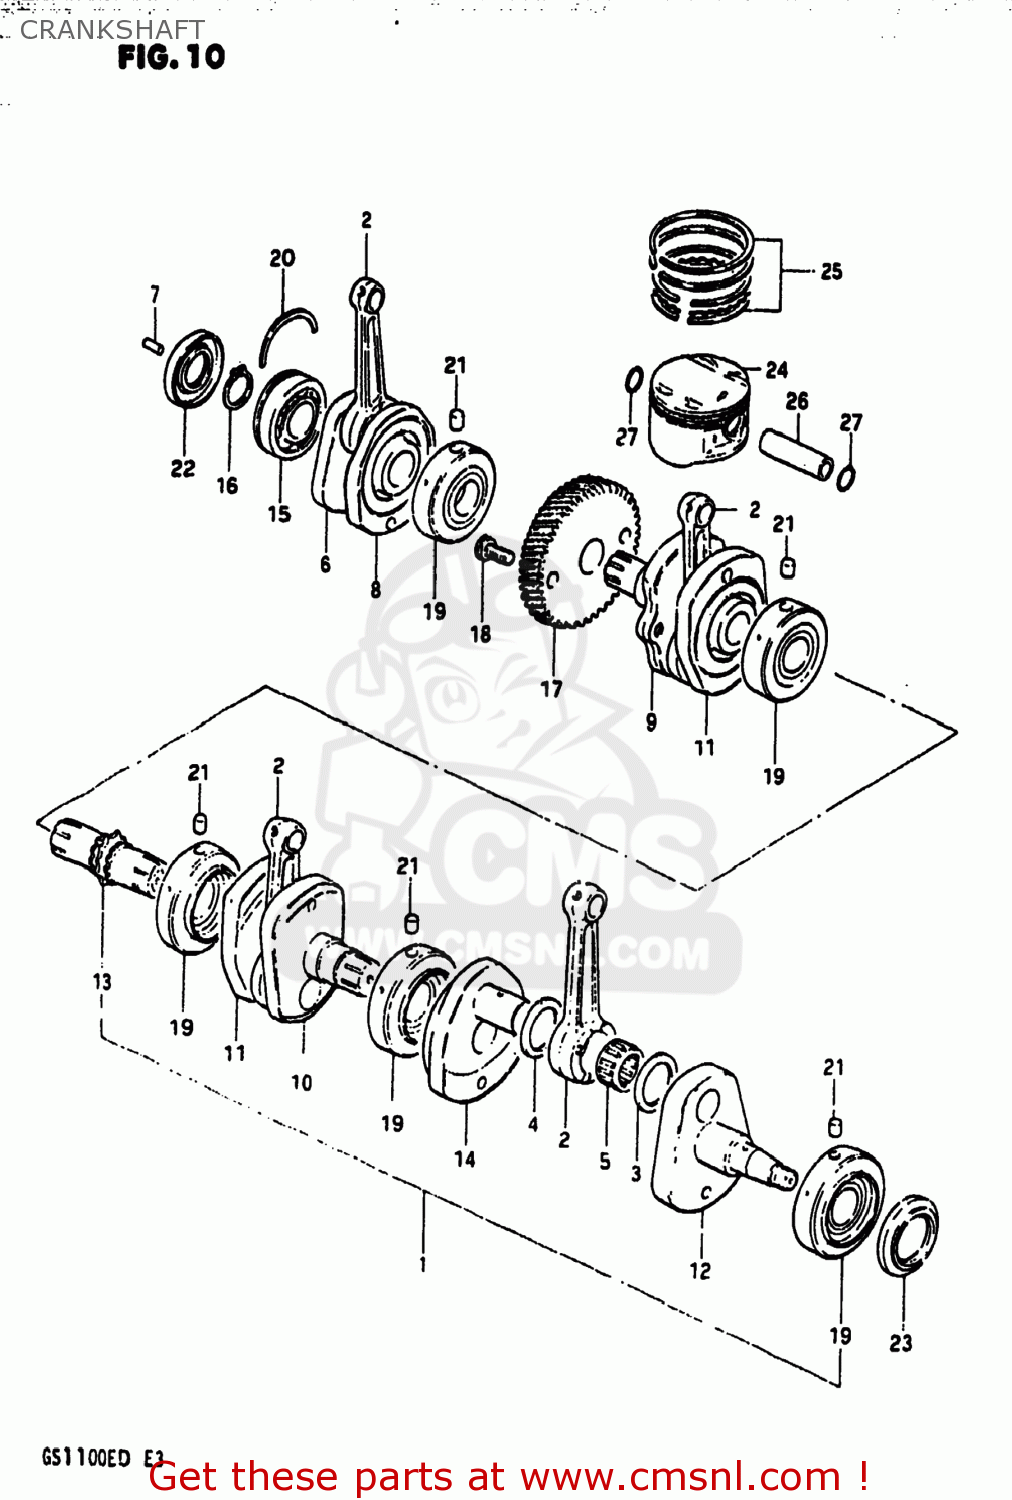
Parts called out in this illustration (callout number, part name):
1	CRANKSHAFT ASSEMBLY
2	CONNECTING ROD
3	WASHER(31X48.5X1)
4	WASHER(31X48.5X2)
5	BEARING(31X39X21)
6	CRANKSHAFT,RIGHT
7	PIN
8	WEB,CRANK
9	CRANKSHAFT
10	CRANKSHAFT,MIDDLE,LEFT
11	WEB,CRANK,MIDDLE
12	CRANKSHAFT,LH
13	SHAFT,TIMING CHAIN DRIVE
14	WEB,CRANK,LEFT
15	BEARING(30X72X19)
16	CIRCLIP,30MM
17	GEAR,PRIMARY DRIVE
18	BOLT
19	BEARING
20	C RING
21	PIN
22	SEAL,OIL(30X72X11)
23	SEAL,OIL(47.3X60X6.5)
24	PISTON
25	RING SET,PISTON
26	PIN,PISTON
27	CIRCLIP
